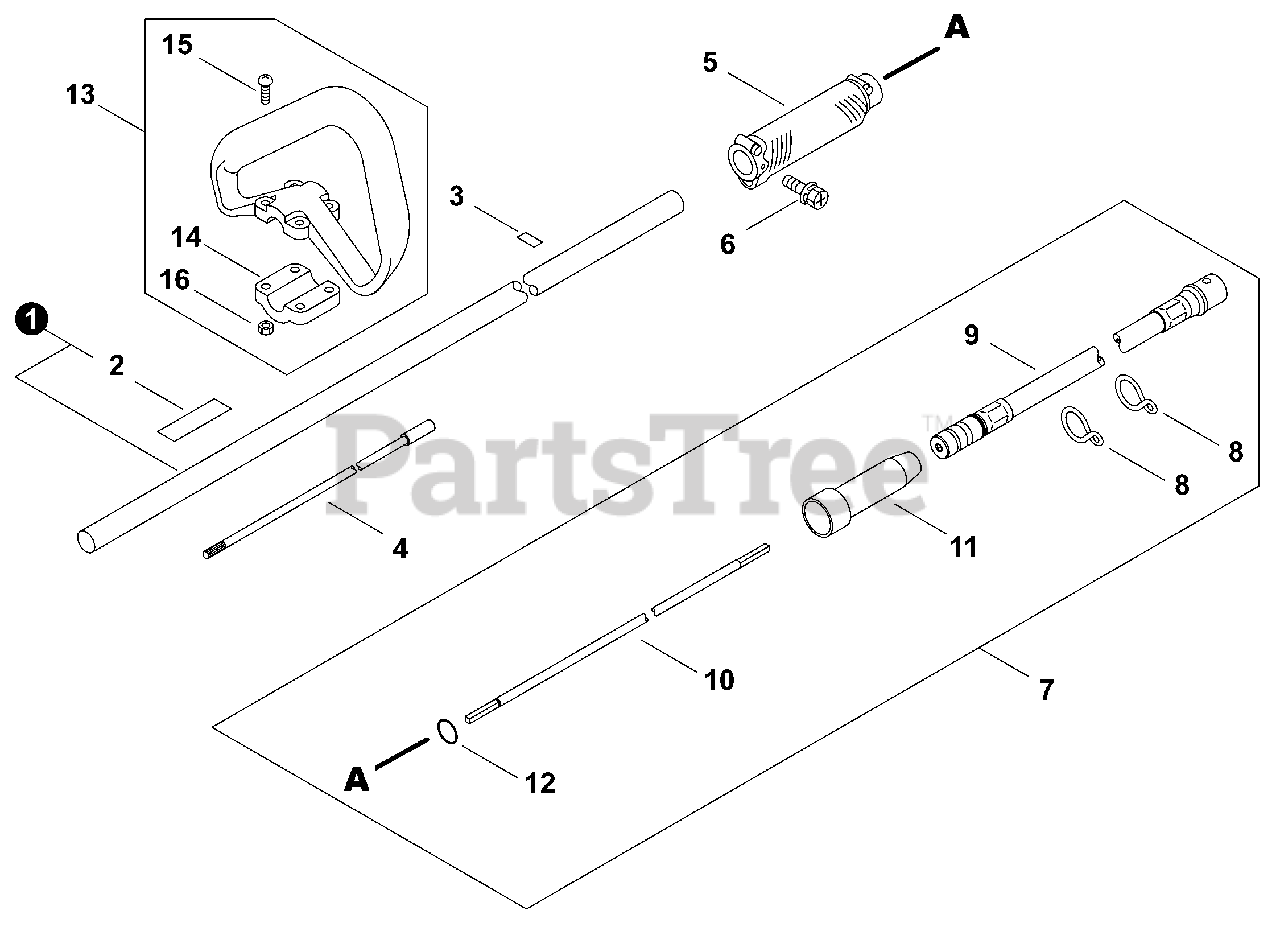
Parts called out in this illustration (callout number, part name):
1	MAIN PIPE ASSY
2	LABEL, CAUTION - ISO
3	LABEL, CAUTION
4	SHAFT, DRIVE
5	CONNECTOR, PIPE
7	DRIVESHAFT - FLEXIBLE
8	HOOK
9	LINER - FLEXIBLE
10	DRIVESHAFT - FLEXIBLE
13	HANDLE ASSY
14	BRACKET, HANDLE
